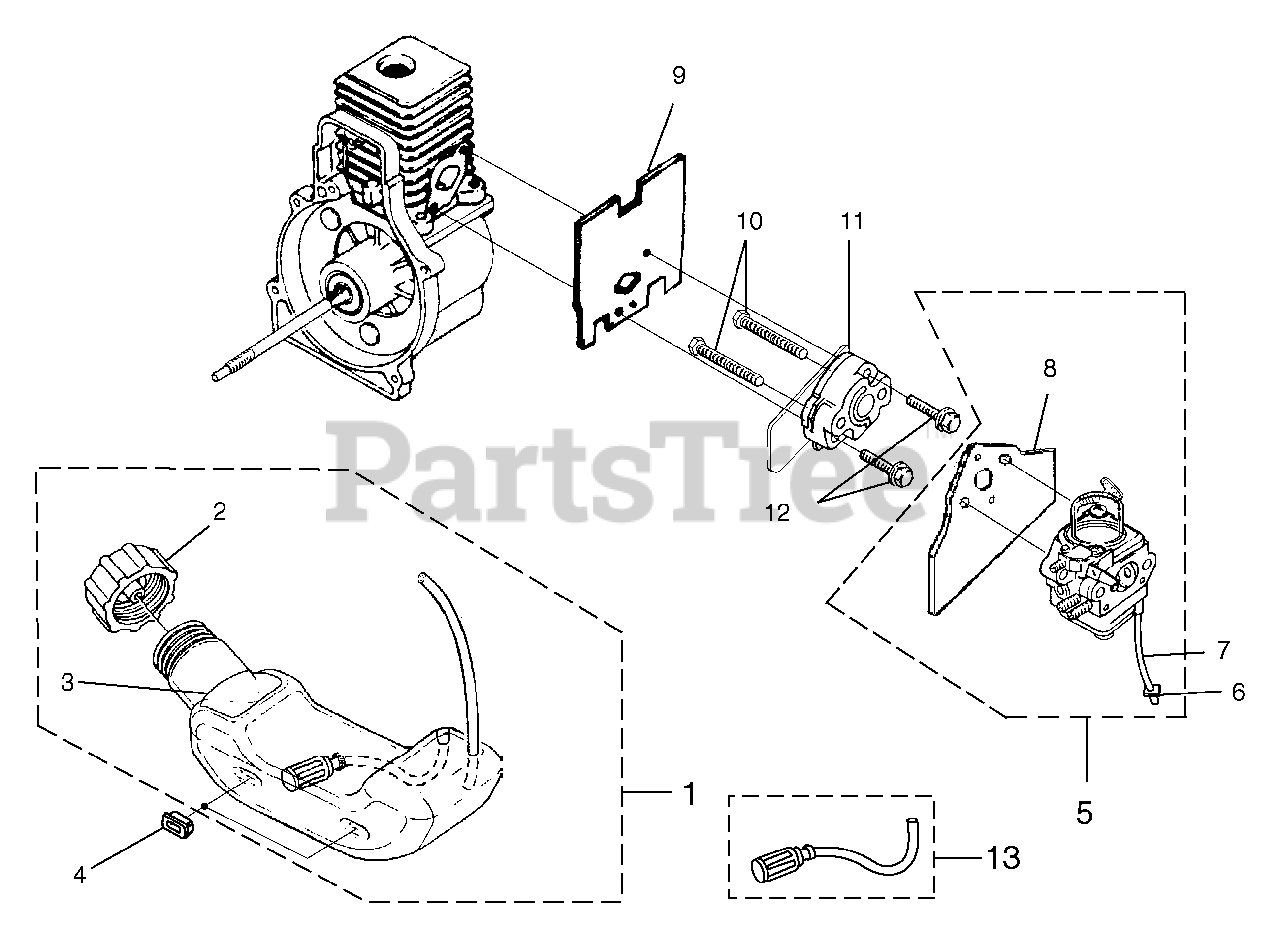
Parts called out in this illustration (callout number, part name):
1	FUEL TANK KIT
2	FUEL TANK CAP
3	HEAT SHIELD
4	RUBBER BUMPER
5	CARBURETOR KIT
6	INLINE FUEL FITTING
7	RUBBER TUBBING (3 in.)
8	CARBURETOR GASKET
9	HEAT DAM GASKET
10	SCREW (10-24 x 1 in. HEX HD. )
11	HEAT DAM
12	SCREW (10-24 x 1.110 in. PAN HD.)
13	FUEL FILTER KIT
